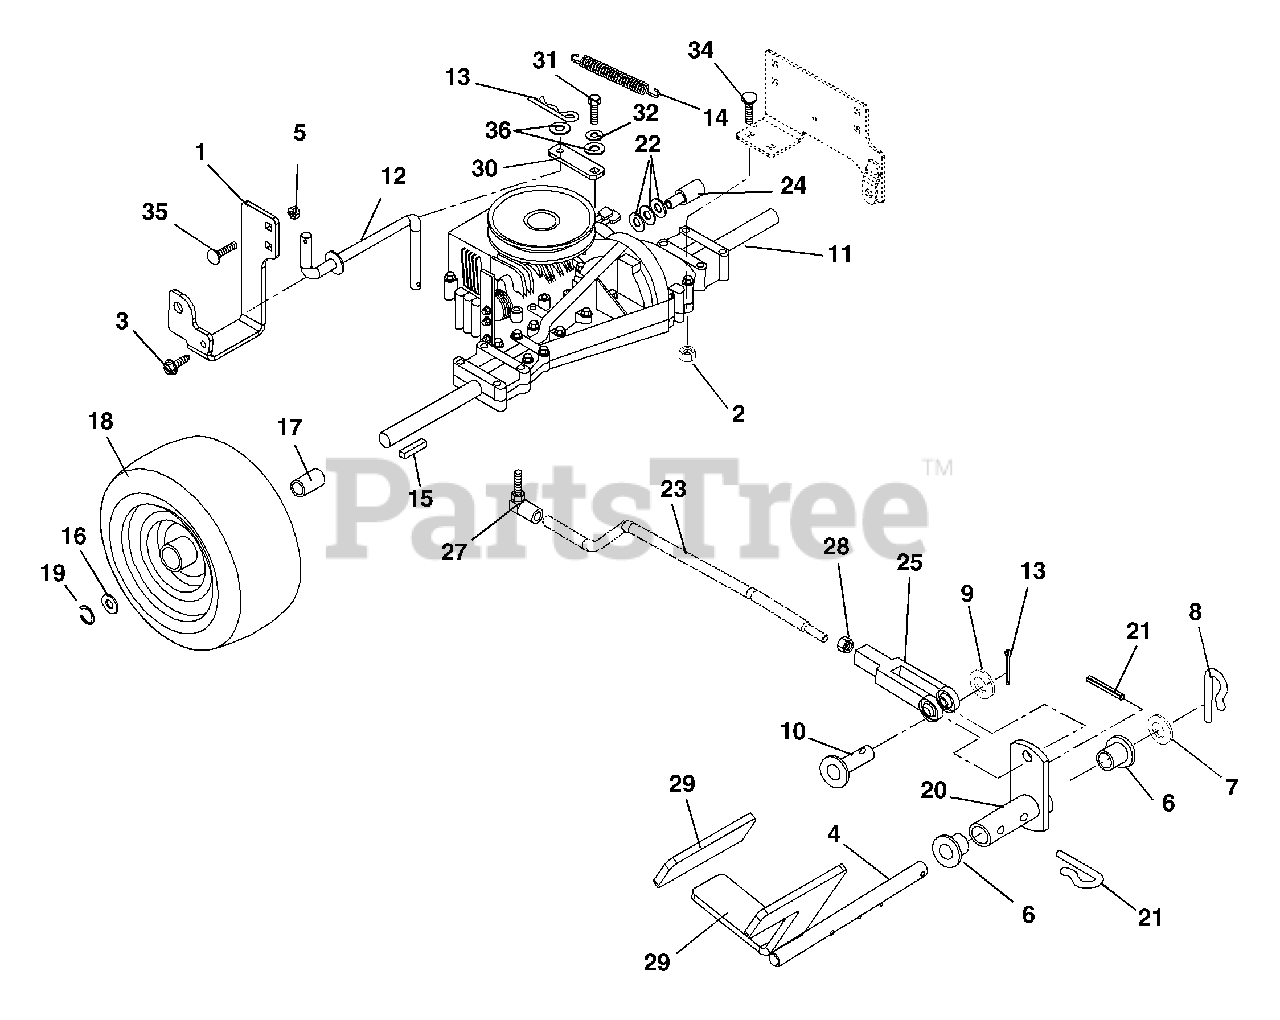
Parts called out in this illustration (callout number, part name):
1	SUPPORT, TRANS
2	NUT-FLG .50-13 PL
3	@SCR-TAP .31-18X.75 HWH TR YWZ
4	WLDMT-FOR&REV PEDAL
5	NUT-LK-TOP-FLG .38-16 BLKZC
6	BSHG-FLG .515X.750X.745X1.00NY
7	WSHR-FL-STL .505X1.00X.062YWZC
8	CLIP, SPRING
9	WSHR-FL-STL .328X.87X.179 YWZC
10	PIN-CLEV .312X.822 HDND PL
11	TRANS. PEERLESS LTH-2000-020
12	ROD, TRANS DISCONNECT
13	PIN-HAIR, ENDRIES #25 YWZC
14	SG-TENS .043X.44X3.31 WLD 5.8
15	KEY-SQ .188X2.0X.188 SAE 8630
16	WSHR-FL-STL .755X1.25X.125 YZ
17	SPACER WHEEL .75X1.0X1.25
18	ASSY-TIRE&WHEEL 16 X 6.5 X8
18	ASSY, WHL/TIRE 480 X 8
18	TIRE 16X6.50-8 2 PLY
19	RG-RTNG-EXT .750X.050
20	WLMDT-SHIFT ROD & HUB
21	@PIN-CTR .12X1.00 EXTPRSQCT YZ
22	WSHR-FL-STL .505X1.00X.062YWZC
23	ROD, RER SHIFT
24	TRUNNION
25	YOKE, .312-24 X 2.25
26	WSHR-FL-STL .390X.75X.125 YWZC
27	BALL JOINT
28	NUT-LK-NYL .375-24 W/INSR YWZC
29	GRIP, PEDAL
30	TAB, TRANS DISCONNECT
31	BLT-HEX .25-28X.75 GR5 YWZC
32	@WSHR-LK .25X.062 REG YWZC
33	WSHR-FL-STL .328X1.0X.094 YWZC
34	@BLT-RDHDSQNK .31-18X2.50 G5YZ
35	BLT-RDHDSQNK .38-16X.75 G5BZ
36	@WSHR-FL-STL.38X.875X.083 YWZC
